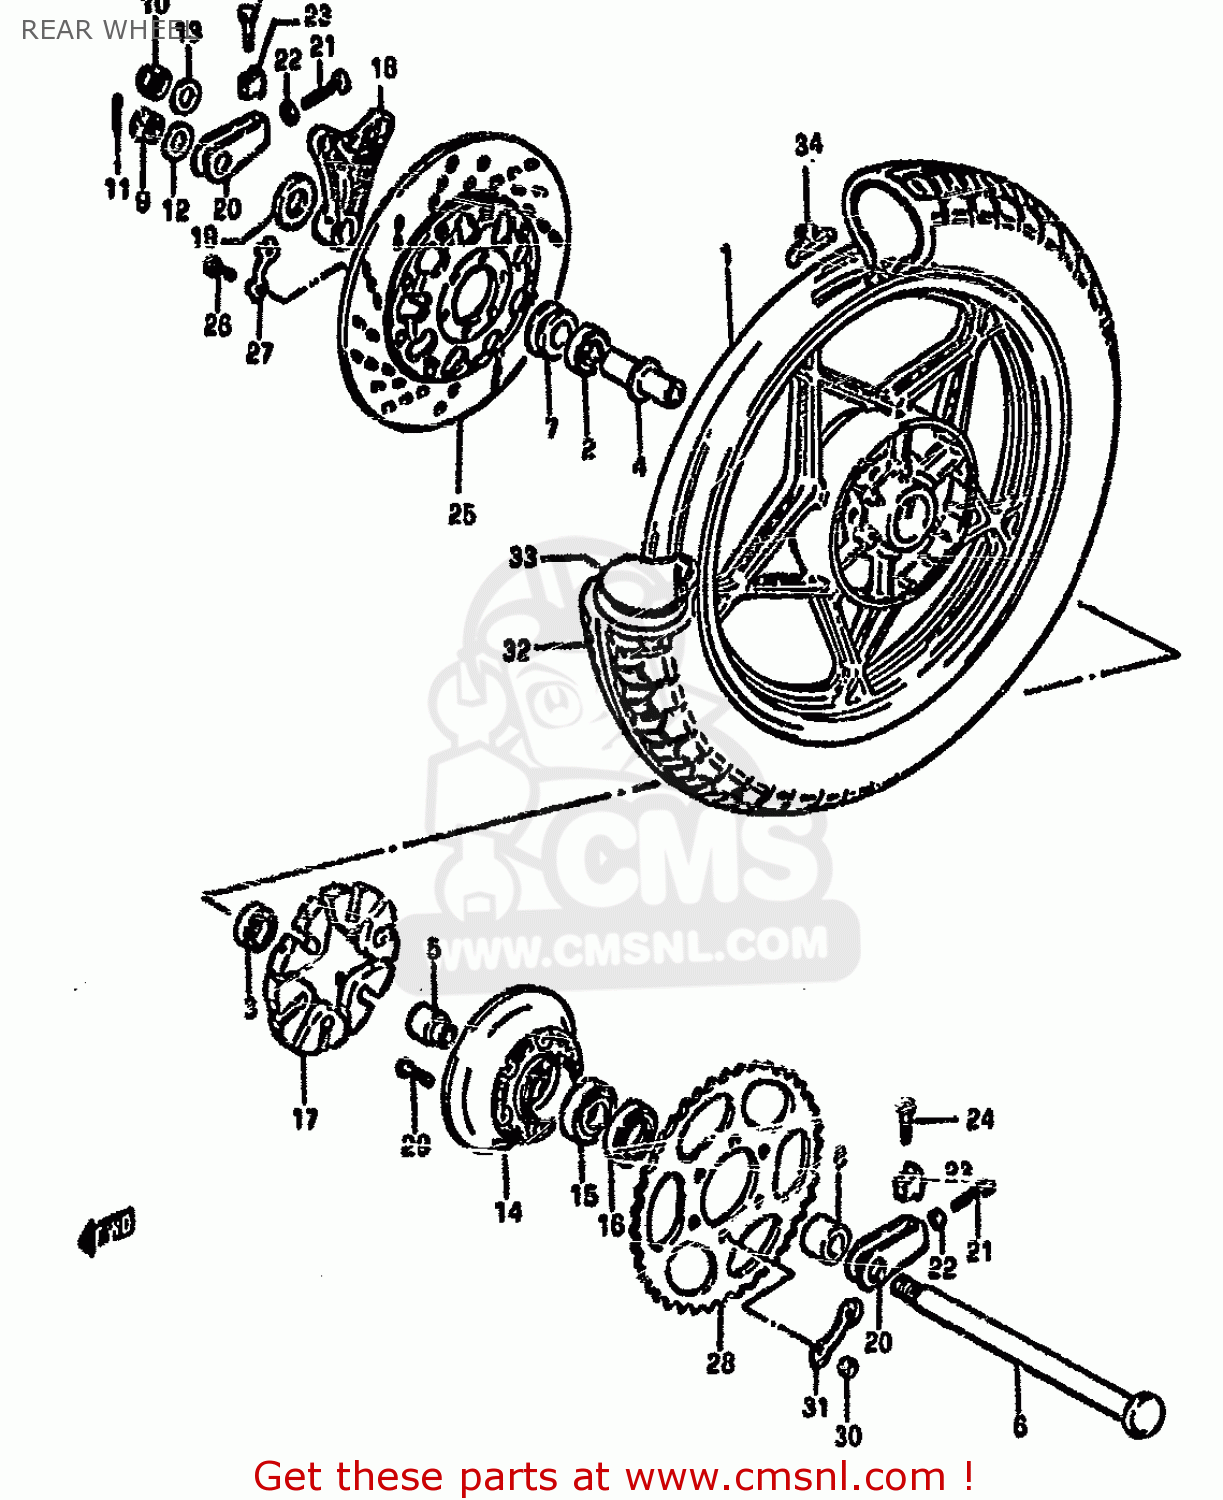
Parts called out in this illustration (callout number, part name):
1	WHEEL,REAR
2	BEARING
3	BEARING
4	SPACER,REAR HUB BEARING
5	RETAINER,REAR SPROCKET D
6	AXLE,REAR
7	SPACER,REAR AXLE
8	SPACER (17X33X21.1)
9	NUT
10	NUT
11	PIN,COTTER
12	WASHER (17X30X3.2)
13	WASHER
14	DRUM,REAR SPROCKET MOUNT
15	BEARING
16	SEAL,OIL(33X62X7)
17	ABSORBER,REAR HUB SHOCK
18	BRACKET,RR,CALIPER
19	SPACER,REAR CARIPER BRACKET
20	ADJUSTER,CHAIN
21	BOLT
22	NUT
23	SUPPORTER,CHAIN ADJUST
24	BOLT
25	DISC,BRAKE
26	BOLT(8X30)
27	WASHER
28	SPROCKET,RR
29	BOLT
30	NUT
31	WASHER
32	TIRE
33	TUBE ASSEMBLY,WHEEL,INNER
34	BALANCER,WHEEL
